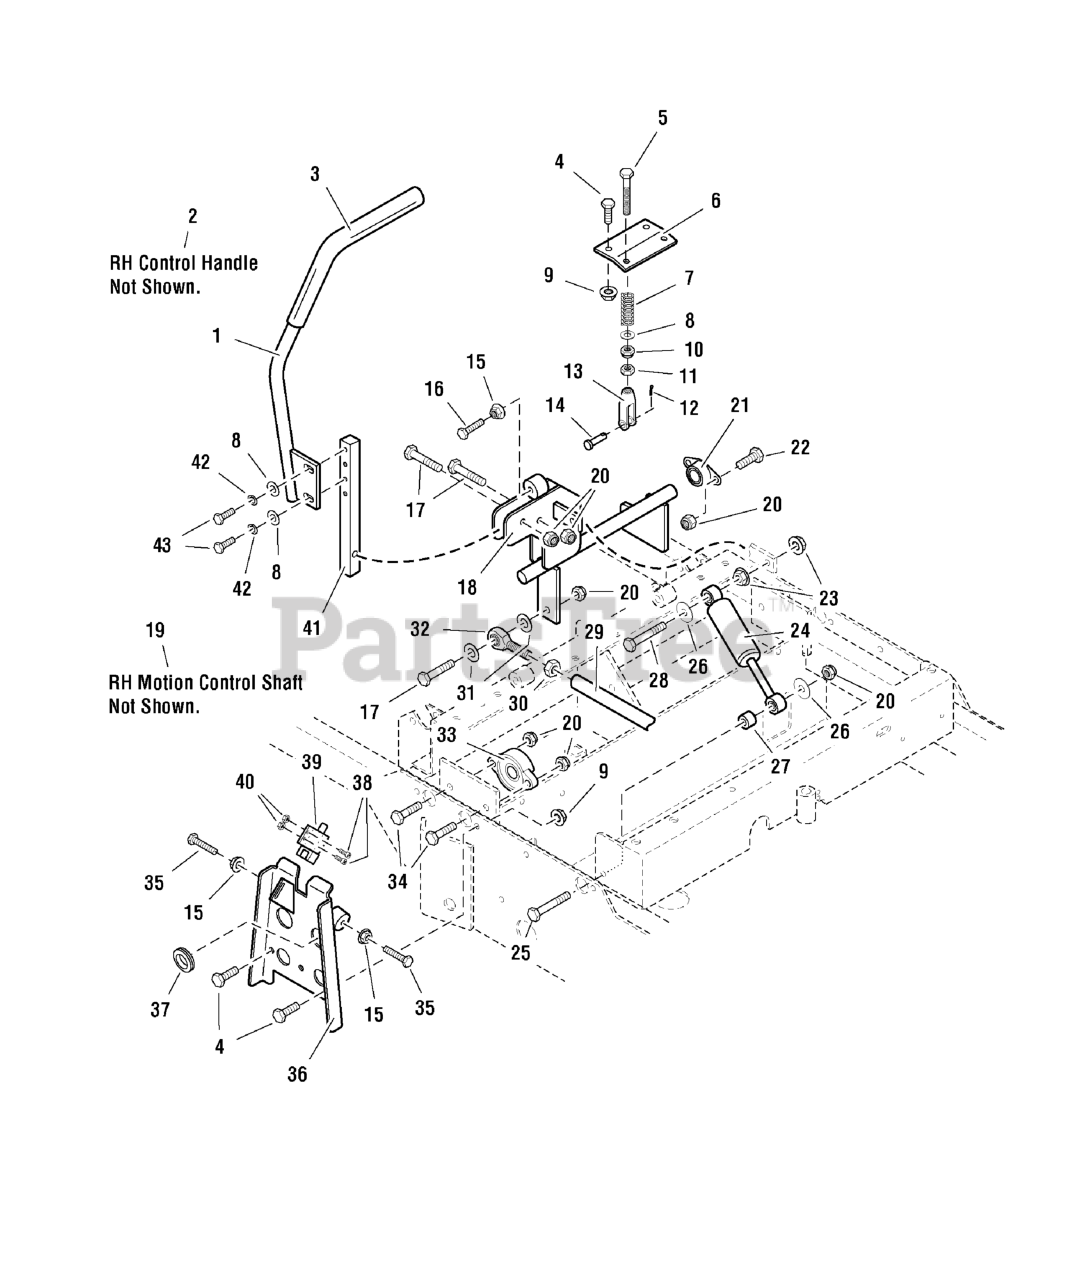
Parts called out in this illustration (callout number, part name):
1	CONTROL HANDLE - LH
3	GRIP, Foam
4	BOLT, 5/16-18 X 3/4 GD5
5	REVERSE RETURN BOLT
6	NEUTRAL RETURN PLATE
7	SPRING, Compression
8	WASHER, 5/16" SAE
9	NUT, 5/16-18 HEX SERRATED FLANGE (LARGE)
10	NUT, 5/16-24 HEX NYLON LOCK
11	NUT, 5/16-24 Hex
12	HAIRPIN CLIP
13	CLEVIS, 5/16-24, Plastic
14	CLEVIS PIN, 5/16 x 1
15	NUT, 5/16-18 HEX SERRATED FLANGE (SMALL)
16	BOLT, 5/16-18 X 1-1/4 GD5 TFL, CZ
17	BOLT, 3/8-16 X 1-3/4" GD5 CZ
18	MOTION CONTROL SHAFT - LH
20	NUT, 3/8-16 HEX NYLON LOCK
21	BEARING, Flange
22	BOLT, 3/8-16 X 1" GD5 CZ
23	NUT, 3/8-16 Hex Serrated Flange
24	KIT, SHOCK W/OUT COIL
25	BOLT, 3/8-16 X 2-1/2" GD5 CZ
26	WASHER, 3/8" Fender
27	SPACER, .39 X .75 X .50, CZ
28	BOLT, 3/8-16 X 2-1/4" GD5 CZ
29	CONTROL ROD
30	NUT, 3/8-24 Hex
31	WASHER, 3/8 SAE
32	BALL JOINT, 3/8-24 Male
33	BEARING, Flange
34	BOLT, 3/8-16 X 1-1/4" GD5 CZ
35	BOLT, 5/16-18 x 2 TFL
36	NEUTRAL LOCK PLATE
37	GROMMET, 7/8"
38	SCREW, #10-24 X 1 RS, CZ
39	SWITCH, Plunger, NO/NO
40	NUT, #10-24 Hex
41	MOUNT, CONTROL ARM - BLK
42	WASHER, 5/16 LOCK CZ
43	BOLT, 5/16-18 X 3/4 GD5
